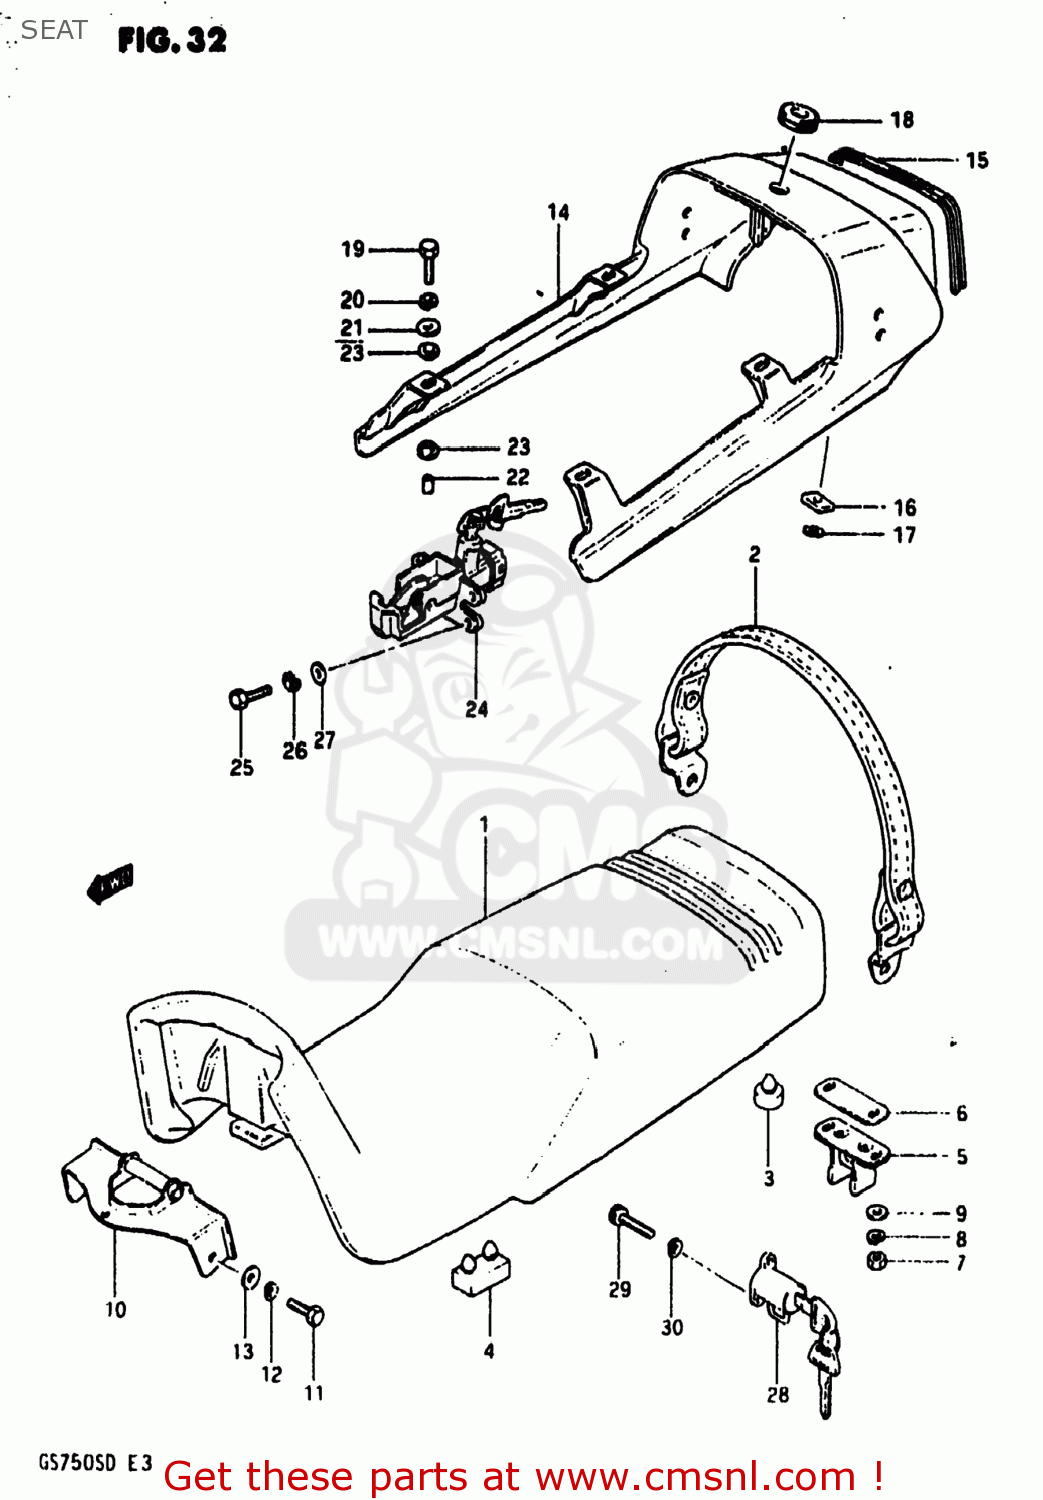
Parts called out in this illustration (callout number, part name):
1	SEAT ASSEMBLY
2	BAND,SEAT GRIP
3	CUSHION
4	CUSHION
5	STRIKER,SEAT LOCK
6	SHIM,SEAT LOCK STRIKER
7	NUT 6MM
8	LOCK WASHER
9	WASHER
10	PLATE,SEAT HOOK FR
11	BOLT
12	LOCK WASHER
13	WASHER
14	COVER,SEAT TAIL
15	MOLE,SEAT TAIL COVER
16	CUSHION,SEAT TAIL
17	NUT
18	GROMMET,SEAT LOCK HOLE
19	BOLT
20	LOCK WASHER
21	WASHER (6.5X24X1.6)
22	SPACER (7X10X12)
23	CUSHION
24	LOCK SET
25	BOLT
26	LOCK WASHER
27	WASHER
28	LOCK ASSEMBLY,HELMET
29	BOLT
30	LOCK WASHER
